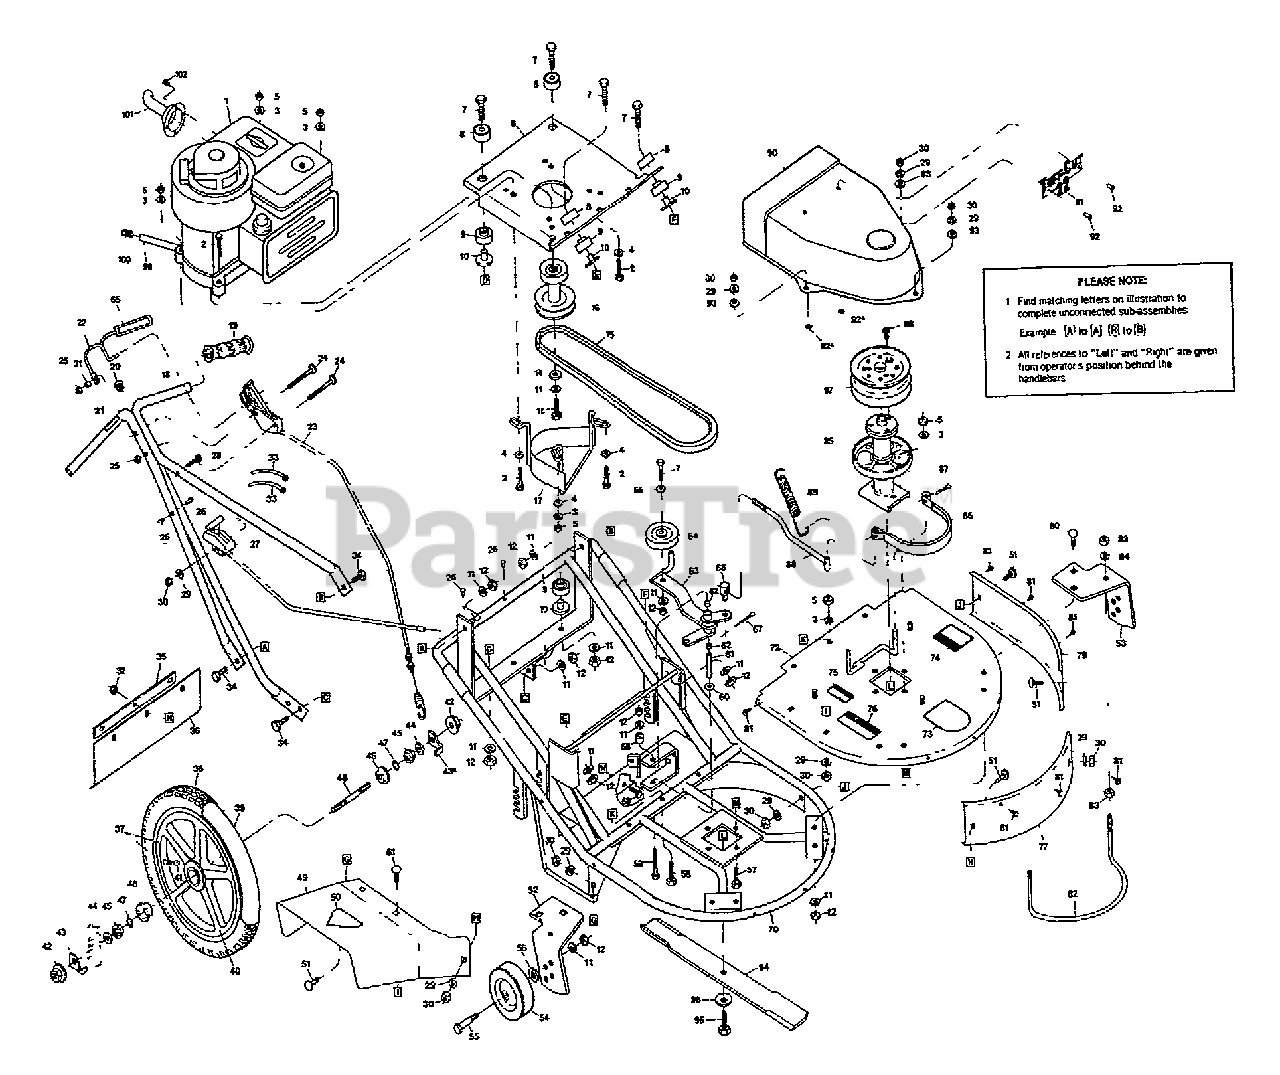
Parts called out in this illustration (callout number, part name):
2	SCR-HH 5/16-18X1.75
3	WASHER-LK .312 ZP
4	WASHER-.88X312X.08 ZP
5	NUT-HEX 5/16-18 ZP
6	BASE-ENGINE PNT
7	SCR-HH 3/8-16X2.0 G5 ZP
8	REBOUND MOUNT-24"
9	LOAD CARRYING MOUNT-24"
10	TUB-SPACER 24"
11	WASHER-LK .375 @ DEPL
12	NUT-HEX 3/8-16 ZP
13	SCR-HH 3/8-24X1.5 G5
14	WASHER-1.0X.438X.104 ZP
15	BLADE-V BELT
16	PULLEY-ENGINE
17	GUIDE-BELT PNT
18	ASSM-HANDLEBAR 22" PUSH INCL. 19 AND 21
19	GRIP-HANDLEBAR
20	PLUG-METAL CAP
21	DECAL-STARTING INST
22	ASSM-BLADE CONTROL HANDLE INCL. 65
23	CABLE-BLADE DRIVE (CABLE AND LATCH)
24	SCR-PHP M10-24X4.0 ZP
25	NUT-HEX LOCK #10-24 PL
26	PLUG-HOLE
27	SPEED CONTROL-ENGINE
28	SCR 1/4-20X1.5 PL CSHH
29	WASHER-LK .25 ZP
30	NUT-HEX 1/4-20 ZP
32	NUT-H/LK 5/16-18
33	TIE-RED
34	SCR-HH 3/8-16X.75 G5 ZP
35	BRKT-PROT TRAILER PNT
36	TRAILER-MOWER
37	ASSM-TIRE & WHEEL {38,39,40,41,42,44,45,46, 47, 48}
38	TIRE-16 X 2.125
39	TUBE-16"
40	ASSM-16" RIM {42,44,45,46,47,48}
41	CAP-VALVE
42	NUT-HF/LK 3/8-24 WHIZ
43	TAB-WHEEL LOCK RH
43A	TAB-WHEEL LOCK LH
44	NUT-LOCK 3/8-24 PL
45	NUT-ACORN 3/8-24 ZP
47	BEARING-WHEEL
48	AXLE-WHEEL
49	CHUTE-DISCHARGE W/DECAL
50	DECAL-BLADE WARNING
51	SCR-CARR 1/4-20X.375
52	HANGER-RT WHL PNT
53	HANGER-LT WHL PNT
54	ASSM-TIRE&WHEEL 6X1.50
55	SCR-SHLDR 3/8-16X1.406
56	WASHER-FLAT 3/8 SAE
56	SCREW
57	SCR-HH 5/16-18X1.0 G5 ZP
59	SCR-HH 3/8-16X4.5 G5
60	SHIM-WASHER
61	TUBE-PIVOT
62	BEARING-SLEEVE
63	ARM-IDLER W/BUSHINGS (INCL. 2 BEARINGS REF. NO. 62)
64	PULLEY-IDLER
65	STICKER-BLADE BAIL
66	TRUNNION
67	PIN-COTTER .094X1.0
68	SPACER-.625X.387X1.0 ZP
69	SCR-HHC 5/16-18X.75 GR 5 ZP
70	ASSY FRAME PAINTED
71	REF. NO. NOT USED
72	ASSM-DECK TOP 22" {73,74,75,76}
73	DECAL-TUFFCUT LOGO
74	DECAL-WARNING PROCEDURES
75	DECAL-CAUTION BELT COVER
76	DECAL-DANGER GUARD
77	WRAP-FRONT 22" PNT
78	REF. NO. NOT USED
79	WRAP-LH PNT
80	SCR-CARR 3/8-16X1.00
81	SCR-HW M10-16X.75 SELT DR
82	BUMPER-22" PNT
83	NUT-HEX JAM 1/2-13
84	WASHER-LK .5
85	KIT-SPINDLE TUFFCUT I&II (INCL. PULLEY REF NO. 97 AND SPINDLE MOUNTING HARDWARE)
86	BRAKE BAND & LINING
87	PIN-COTTER 1/8X3/4
88	ROD-BRAKE ENGAGEMENT
89	SPRING-SPINDLE BRAKE
90	COVER-BELT 22"PUSH MOWER
91	PLATE-NAME 22"
92	RIVET-POPOP
92A	WASHER-RIVETING
93	WASHER-FLAT 1/4 SAE
94	BLADE-22" TUFFCUT NLA
95	SCR-HH 3/8-24 X 1.5" G8
96	WASHER-BELLEVILLE 3/8
97	PULLEY-SPINDLE 3/4 ID (INCL. 3 SCREWS REF NO. 98)
98	SCR-SELFTAP 5/16-18X5/8
99	PIPE-OIL DRAIN
100	PLUG-PIPE 1/4 NPT
101	PIPE-EXHAUST EXT PNT
102	SCR-SELF TAP
